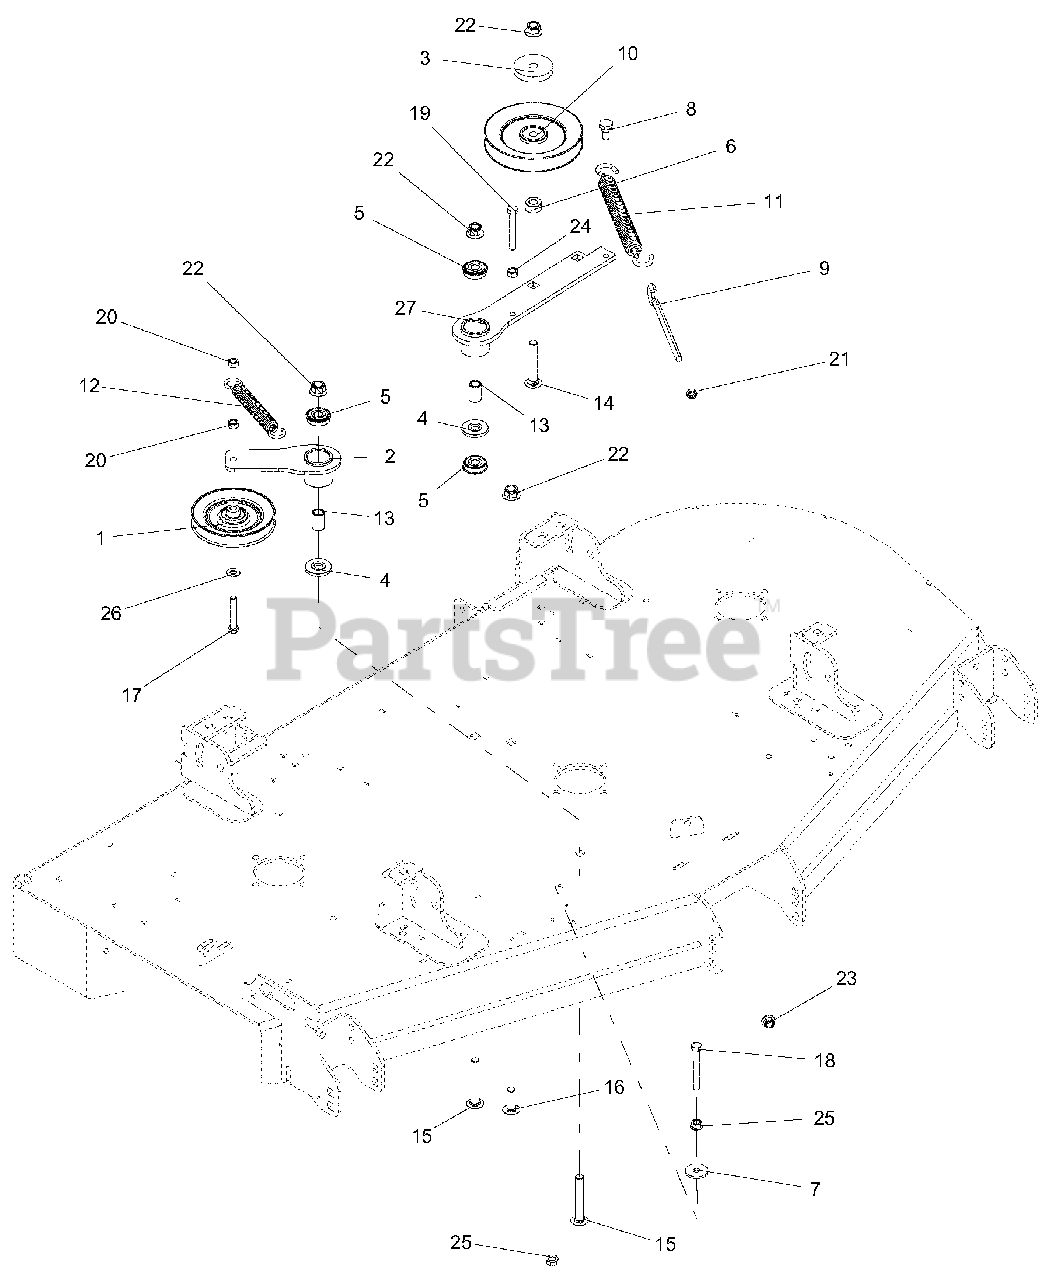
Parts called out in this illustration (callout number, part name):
1	IDLER, V-5.00" W/.69 STANDOFF
2	WLDMT, DECK RH IDLER ARM-BLACK
3	CAP, IDLER BEARING SEALING
4	SPACER, IDLER ARM
5	BRG, BALL .501 X 1.38 X .438 SEALED
6	BSHG, SPCR .502 X .997.50 PM
7	WSHR-FL-STL .406X1.375X.135 YZ
8	BLT, SHLDR EP .38-16X.30 HEX YZ
9	BOLT, .38-16X6.00 .62 DIA EYE
10	SHEAVE, .50" ID X 6.00" OD V-IDLER
11	SPRG, EXTENSION
12	SPRG, EXTENSION
13	SPACER, .510 X .750 X 1.148
14	BLT-RDHDSQNK .50-13X3.00 G5 Y
15	BLT-RDHDSQSHNK .50-13X3.25 YWZC
16	BLT-RDHDSQSHNK .50-13X1.50 YWZC
17	BLT-HEX .38-16X2.25 GR5 YWZC
18	BLT-HEX .38-16X3.00 GR5 YWZC
19	BLT-HEX .38-16X2.75 GR5 YWZC
20	NUT-LK-CTR .38-16 YWZC
21	NUT, JAM .375-16 YWZC
22	NUT-LK-NYL-FLG .50-13 YWZC
23	NUT-LK-NYL-FLG .38-16 YWZC
24	NUT-HEX .38-16 YWZC
25	@NUT-SPNLK-FLG .375-16 YWZC
26	WSHR-FL-STL.406X.812X.065 YWZ
27	WLDMT, DECK PTO IDLER ARM-BLACK
